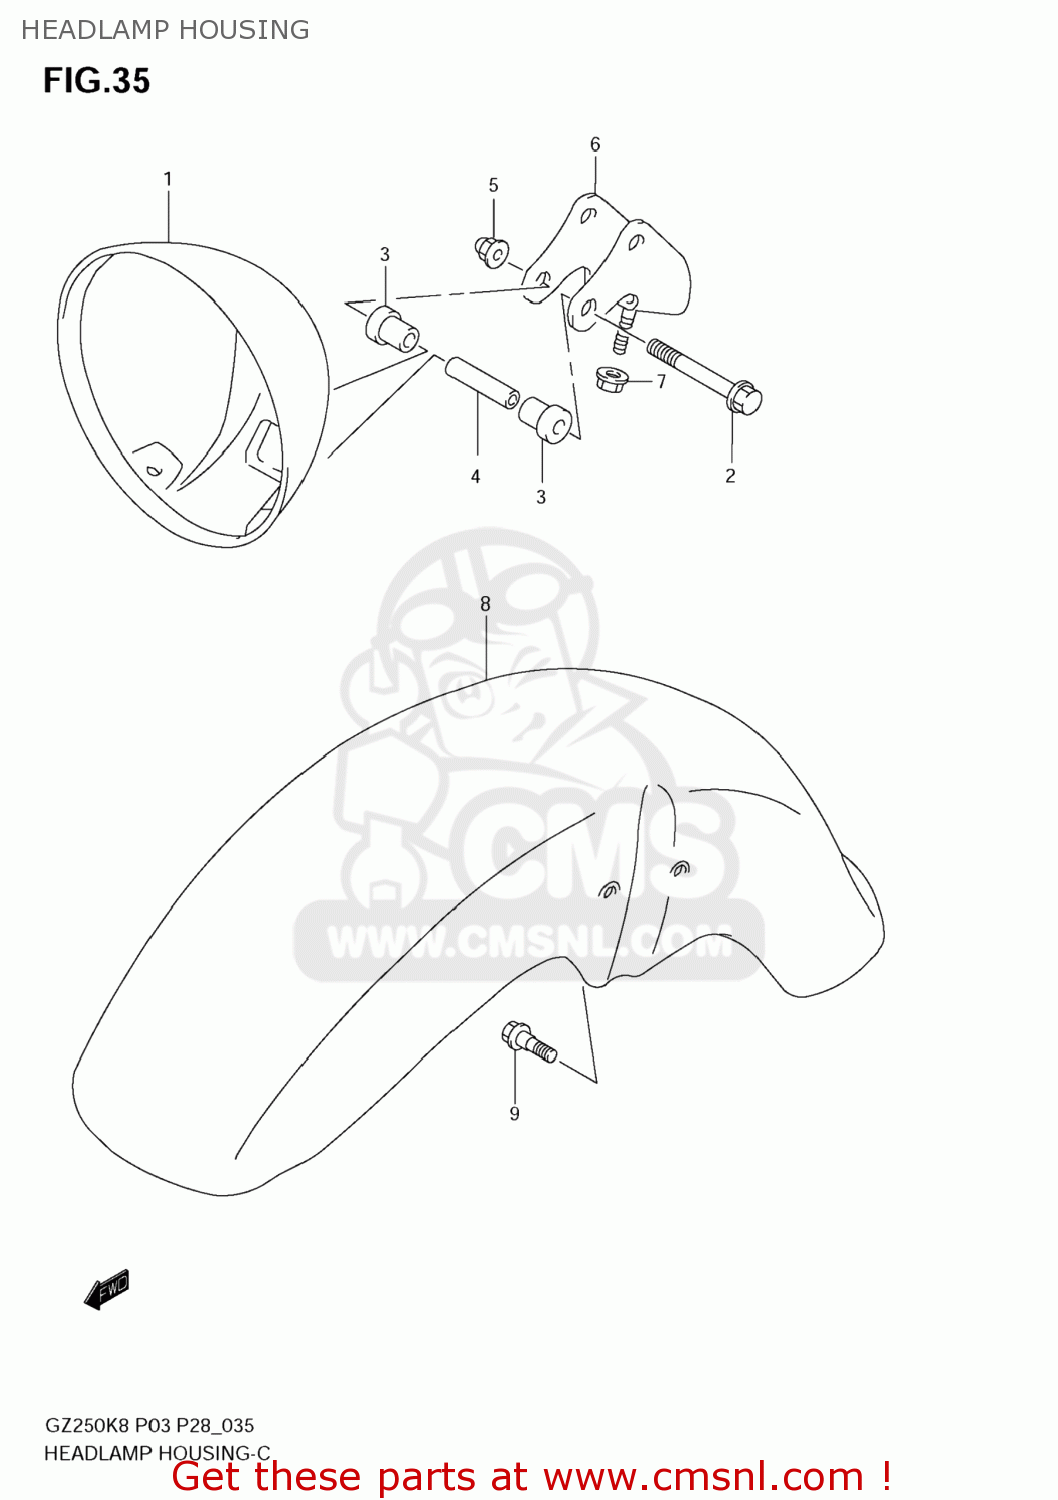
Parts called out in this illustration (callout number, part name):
1	HEADLAMPHOUSIN
2	BOLT
3	CUSHION,HEADLAMP HOUSING
4	SPACER(6.5X9X38.3)
5	NUT
6	BRACKET,HEADLAMP HOUSING
7	NUT
8	FENDER FRONT
9	BOLT(6X16)
